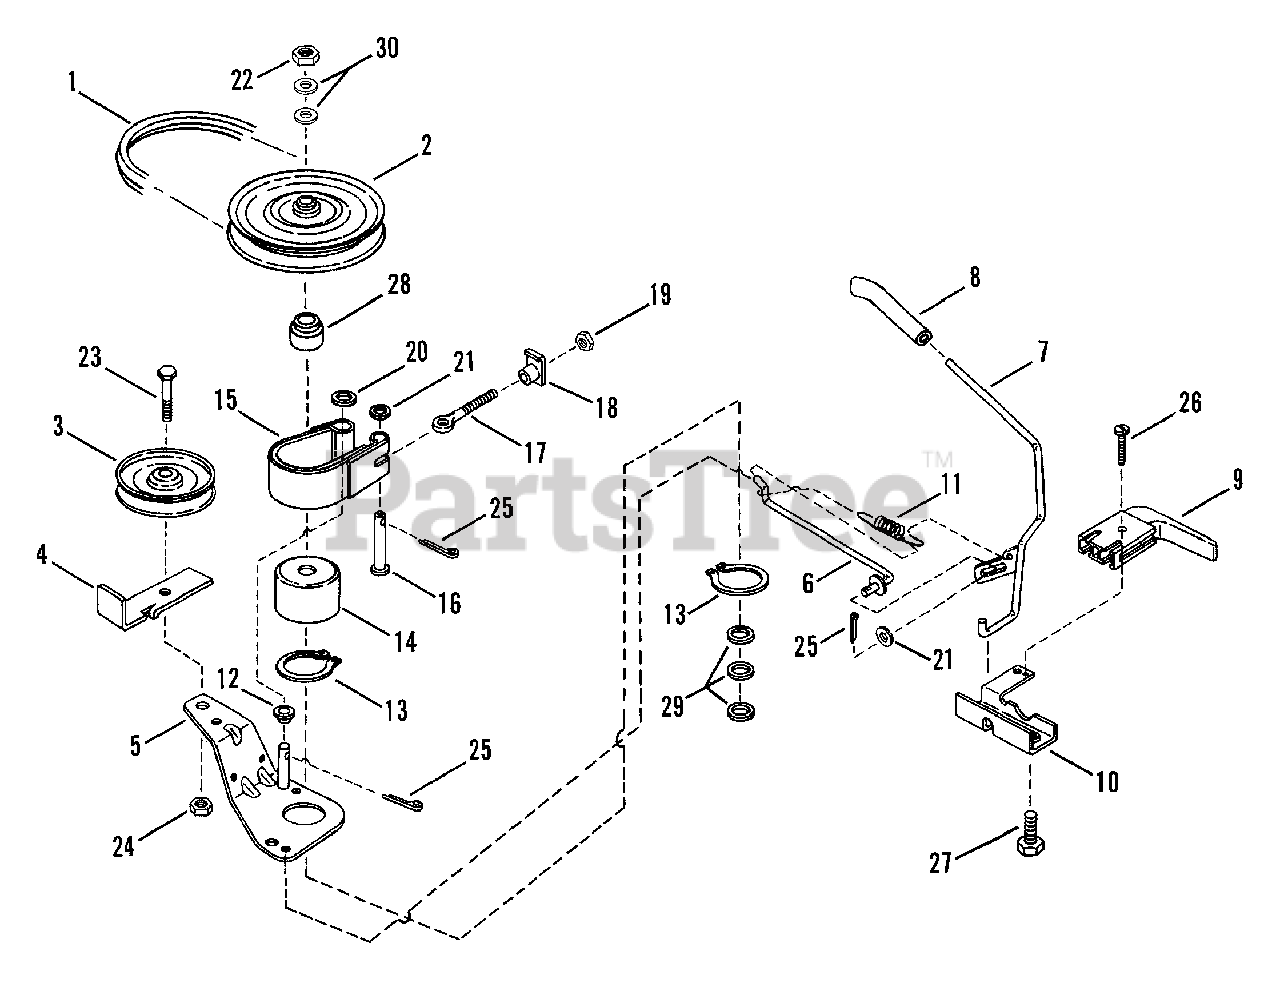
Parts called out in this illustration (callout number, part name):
1	BELT, Drive (25,26,28,30, & 33" Models)
2	PULLEY, Spindle
3	PULLEY, Idler
4	RESTRICTOR, Belt
5	ARM, Idler
6	ROD, Idler
7	HANDLE, Blade ON-OFF (Lever)
8	GRIP, Handle
9	SWITCH, Deck Interlock
10	MOUNT, Handle
11	SPRING, Blade Handle
12	SPACER
13	RING, 2" External Retaining
14	DRUM, Brake
15	BAND, Brake
16	PIN, 1/4x1-5/8" Clevis
17	BOLT, 1/4-20 Eye
18	NUT, 1/4-20 Tee
19	NUT, 1/4-20 Hex
20	WASHER, 3/8" Flat
21	WASHER, 1/4 Flat
22	NUT, 3/4-16 Hex Jam
23	SCREW, 3/8-24x1 3/4" Hex Head Cap
24	NUT, 3/8-24 Hex Lock
25	PIN, 3/32x3/4" Cotter
26	SCREW, #10-32x1" Self-Tapping
27	SCREW, 1/4-20x5/8" Self-Tapping
28	HUB, Pulley
29	WASHER, 49/64x1-1/8" Flat
30	WASHER, 49/64x1-1/2" Flat
